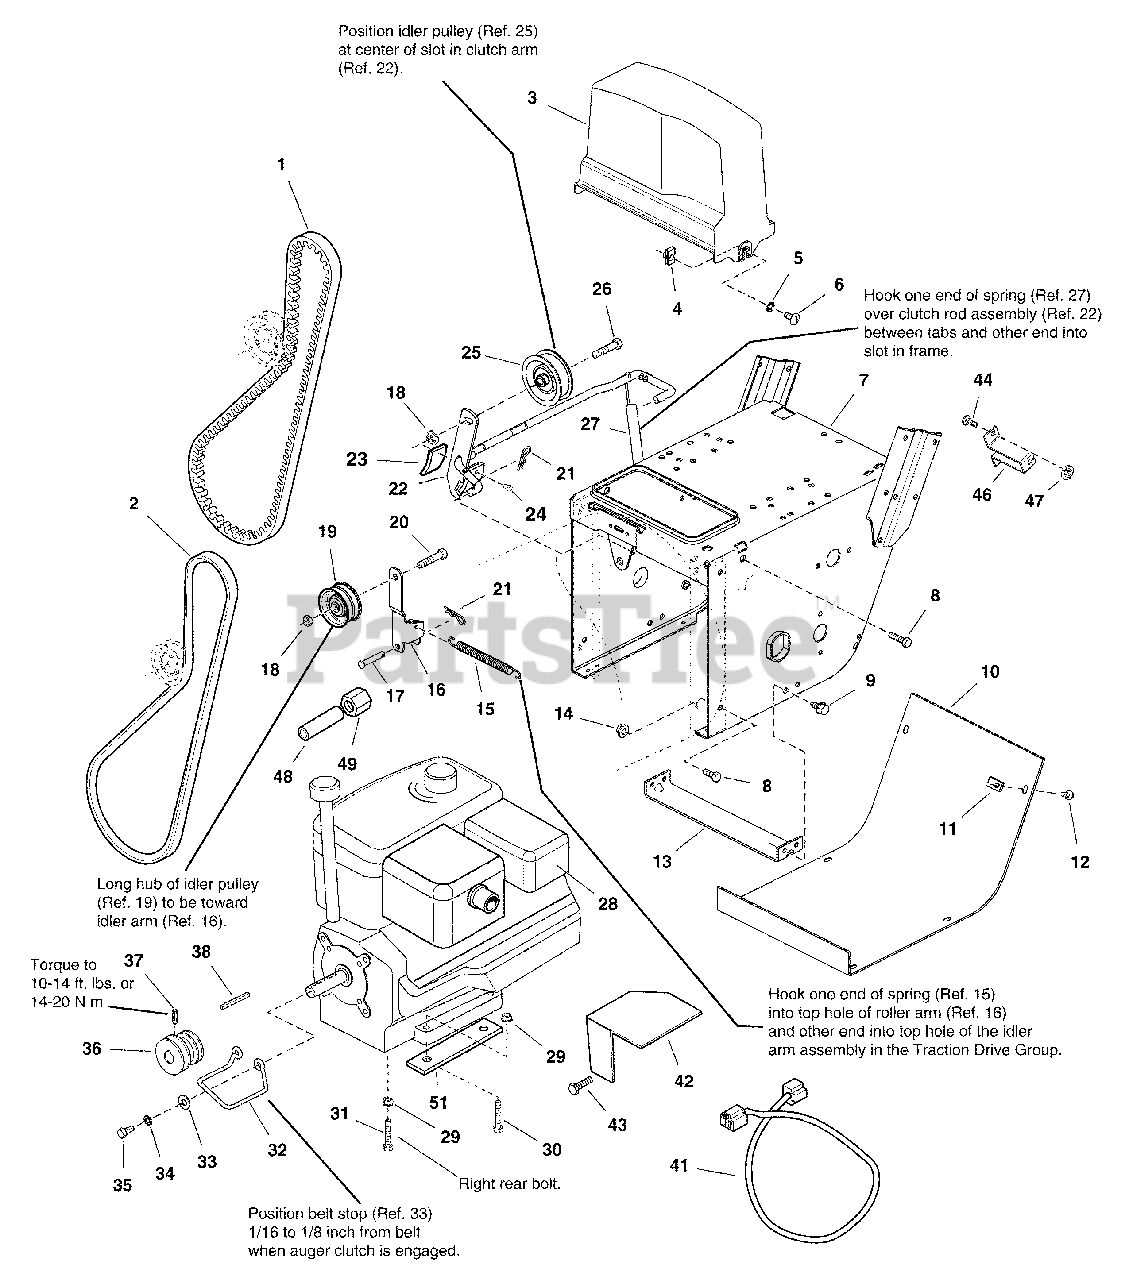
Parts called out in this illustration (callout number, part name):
1	BELT, Traction
2	BELT, Drive Auger
3	GUARD, Belt
4	NUT, Speed, 5/16-18
5	LOCKWASHER, Ext. Tooth, 5/16
6	SCREW, Truss Head, 5/16-18 x 3/4
7	FRAME, Main
8	CAPSCREW, Whizlock, 5/16-18 x 3/4
9	CAPSCREW, Taptite, 5/16-18 x 3/8
10	COVER, Bottom
11	NUT, Speed, 1/4-20
12	CAPSCREW, Taptite,1/4-20 x 1/2
13	SUPPORT, Tie Bar
14	NUT, Hex, Whizlock, 5/16-18
15	SPRING, Idler
16	ARM, Idler, Traction
17	PIN
18	NUT, Hex Flange Whiz Lock 3/8-16
19	PULLEY, Idler
20	CAPSCREW, Hex Head, 3/8-16 x 1-1/2
21	PIN, Hair 5/64 x 1-3/16
22	CLUTCH ROD & BRAKE ASSEMBLY
25	ASSEMBLY, Auger Drive Pulley
26	CAPSCREW, Hex Head, 3/8-16 x 1-3/4
27	SPRING, Extension
29	NUT, Hex, 5/16-18
30	CAPSCREW, Hex Head, 5/16-18 x 1 3/4
31	CAPSCREW, Hex Head, 5/16-18 x 2-1/2
32	GUIDE, Belt
33	WASHER, 11/32 x 3/4
34	LOCKWASHER, 5/16
35	CAPSCREW, Hex Head, 5/16-24 x 3/4
36	PULLEY, Traction
37	SETSCREW, 5/8
38	KEY, Parallel, 3/16 x 13/16 x 7/8
41	CORD, Electrical, 3 Prong (Not a Service Part)
42	GUARD, Muffler
43	CAPSCREW, Hex Washer Head Taptite, #10-24 x 1/2
44	CARRIAGE BOLT, 1/4-20 x 3/4
46	SUPPORT
47	NUT, Hex Washer, 1/4-20
48	PIPE, Oil Drain,
49	CAP, Hex, 1/4-18 NPT
51	SUPPORT, Engine Riser
